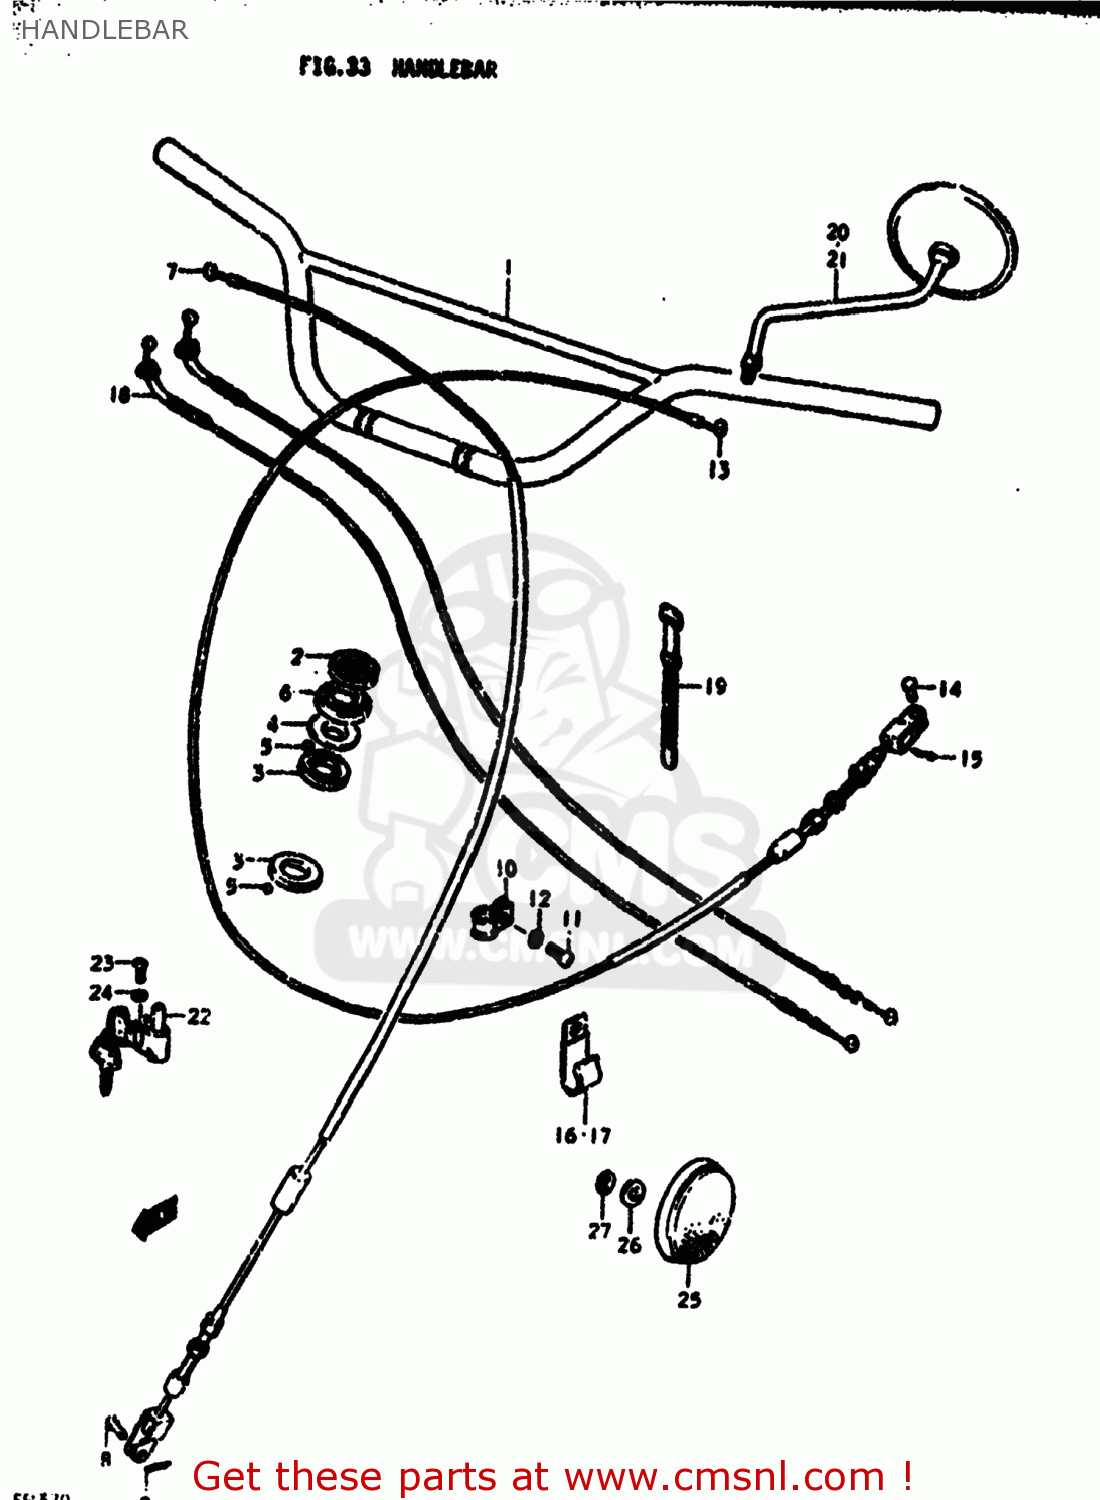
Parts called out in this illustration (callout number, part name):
1	HANDLEBAR
2	NUT,STEERING STEM(25X44X10)
3	LACE,STEERING INNER LWR
4	LACE,STEERING OUTER UPR
5	BALL
6	DUST SEAL,STEERING UPR
7	CABLE ASSEMBLY,FRONT BRAKE
8	PIN(L:17.5)
9	PIN
10	GUIDE,CABLE
11	SCREW
12	LOCK WASHER
13	CABLE ASSEMBLY,CLUTCH
14	PIN(L:15)
15	PIN
16	CLAMP
17	CLAMP
18	CABLE ASSEMBLY,THROTTLE
19	CLAMP(L:120)
20	MIRROR ASSEMBLY,REAR VIEW
21	MIRROR ASSEMBLY,REAR VIEW
22	LOCK ASSEMBLY,STEERING
23	SCREW
24	LOCK WASHER
25	REFLEX REFLECTOR,FR
26	WASHER
27	LOCK WASHER
